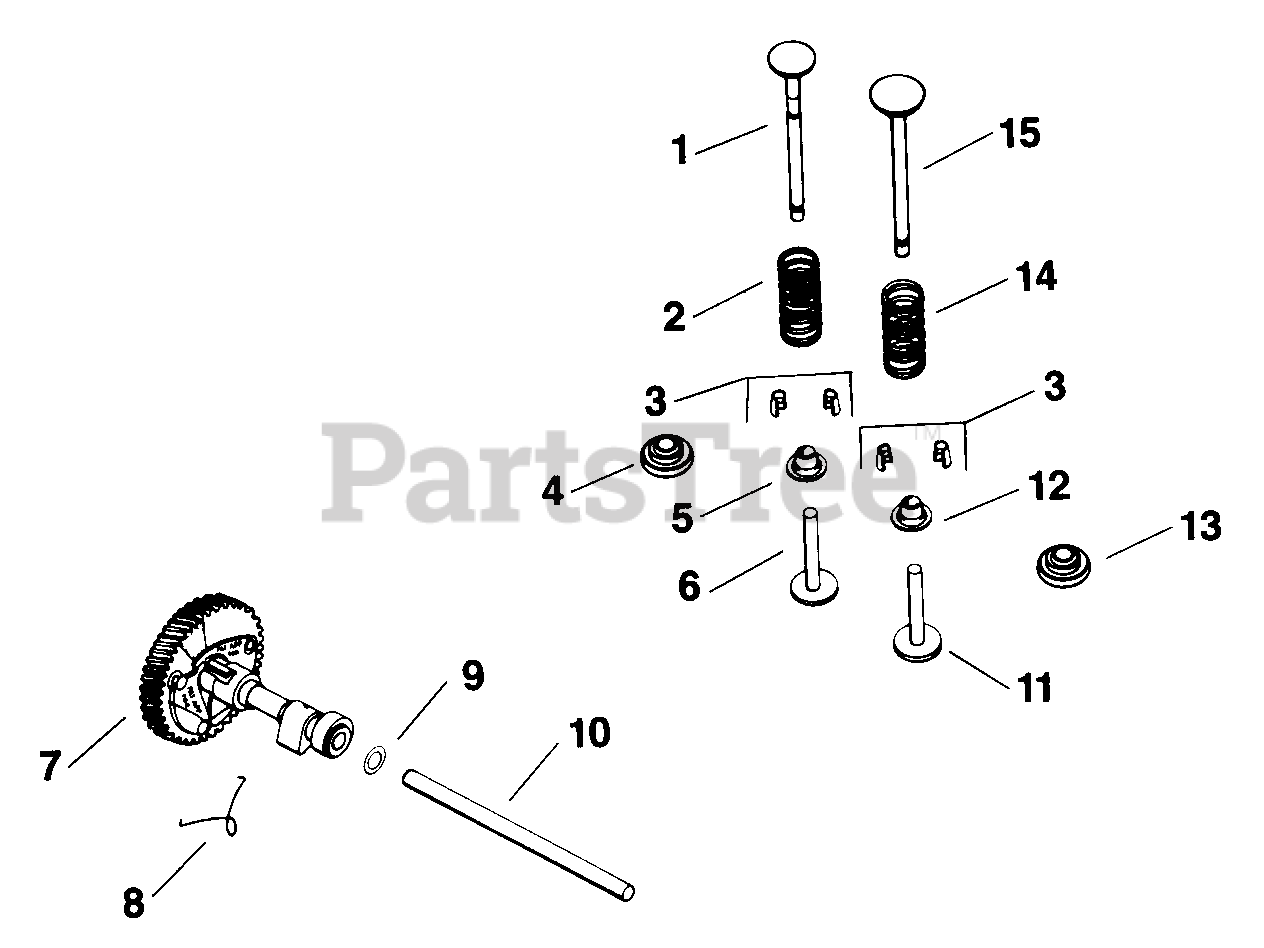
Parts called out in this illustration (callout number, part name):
2	SPRING - DISCONTINUED
3	KIT, RETAINER
5	RETAINER, VALVE SPRING
6	TAPPET - DISCONTINUED
6	TAPPET
7	KIT, CAMSHAFT
8	SPRING, ACTUATING-DISCONTINUED
10	PIN - DISCONTINUED
11	TAPPET - DISCONTINUED
12	RETAINER, VALVE SPRING
14	SPRING - DISCONTINUED
15	VALVE - DISCONTINUED
